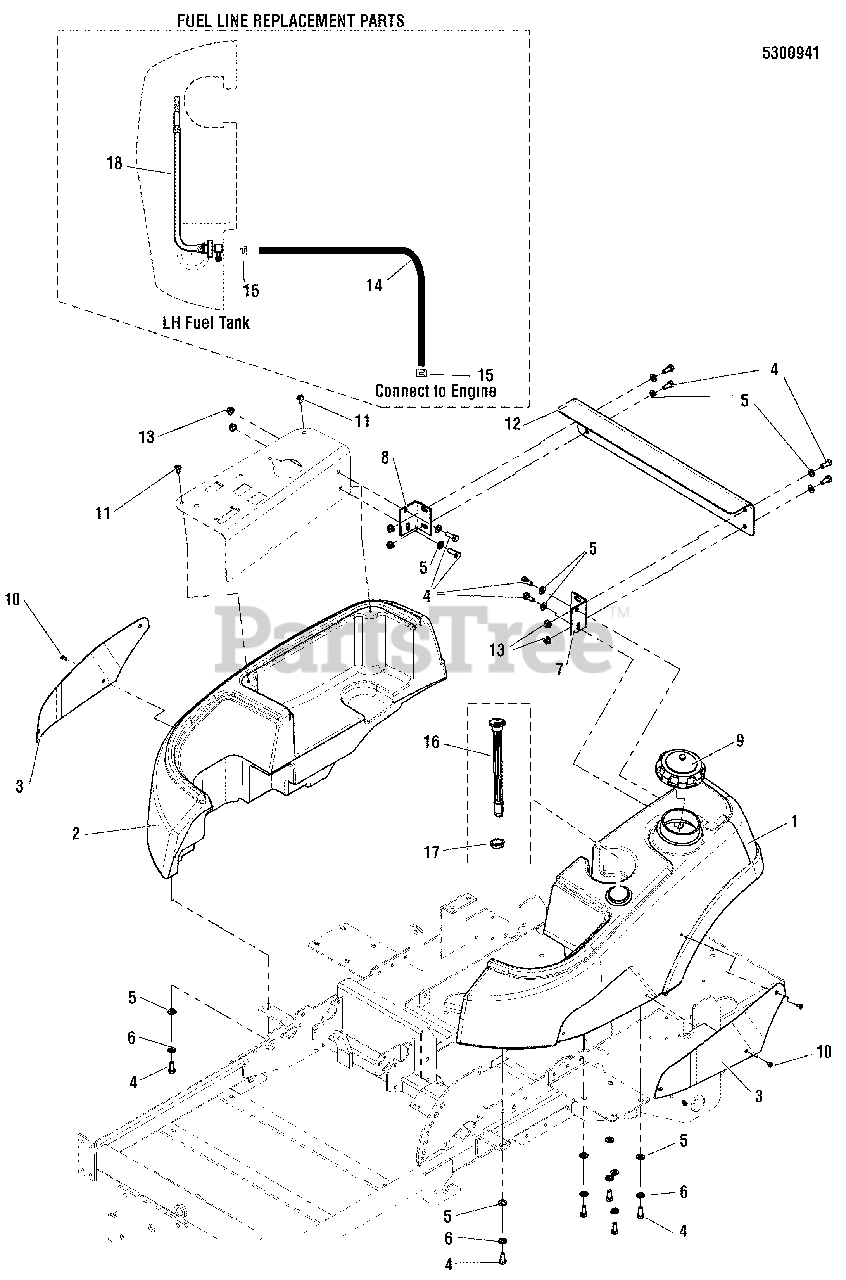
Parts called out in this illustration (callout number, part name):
1	TANK, FUEL, LH
2	TANK, FUEL, RH
3	PLATE, FUEL TANK BADGE
4	BOLT, 5/16-18 X 3/4 GD5
5	WASHER, 5/16" SAE
6	WASHER, 5/16 LOCK YZ
7	BRACKET, REAR SUPPORT - LH - RED
8	BRACKET, REAR SUPPORT - RH
9	FUEL CAP, 3.5", VENTED
10	SCREW, #10-24 X 3/8 ALLEN BHBZ
11	SCREW, 1/4-20 X 1/2 ALLEN BH
12	PLATE, SUPPORT, REAR TANK - SNP RED
13	NUT, 5/16-18 HEX NYLOCK FLANGE
14	HOSE, 1/4 FUEL 28" LONG
15	CLAMP, HOSE, EXTERNAL, 1/2 - RED
16	FUEL GAUGE (SV)
17	GROMMET (SV)
18	PICK UP TUBE ASSM, FUEL TANK (SV)
